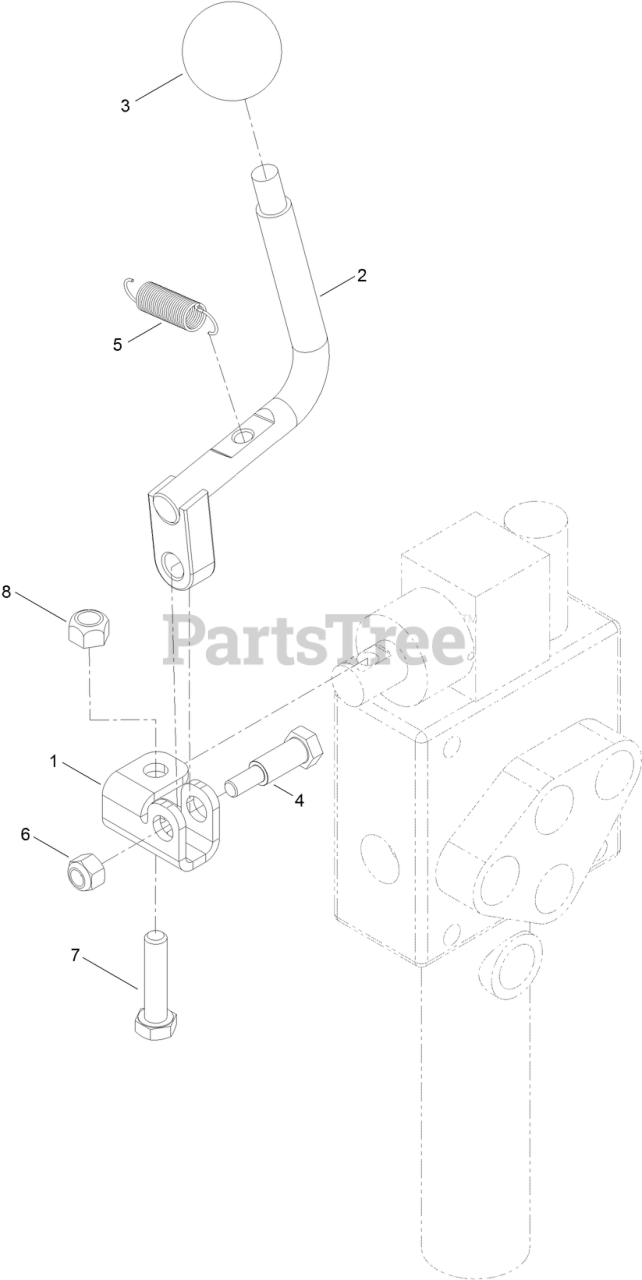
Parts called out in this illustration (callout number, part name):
1	BRACKET-AUXILARY
2	HANDLE ASM
4	BOLT-SHOULDER
5	SPRING-EXTENSION
6	NUT-LOCK, NI
7	SCREW-HH
8	NUT-LOCK, NI
